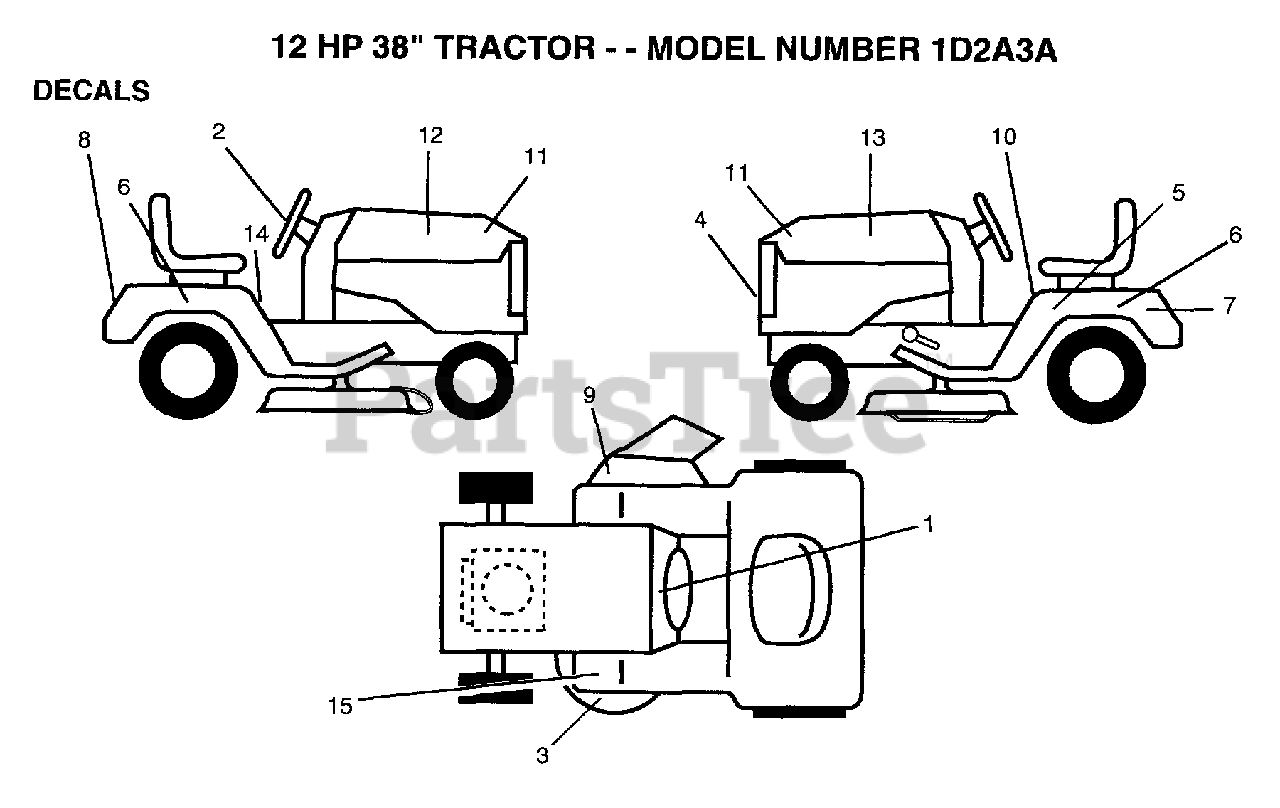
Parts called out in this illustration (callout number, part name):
2	"DECAL,STR WHL"
4	GRILL DECAL
5	IND HGT DECK DECA
6	DECAL.FEND.QUICKS
7	DECAL
8	FENDER DECAL
9	"DECAL, WARNING"
10	DECAL CAUTION
11	DECAL.HOOD.INSERT
14	DECAL.SHIFT.CTR.
15	DECAL, V-BELT 38"
